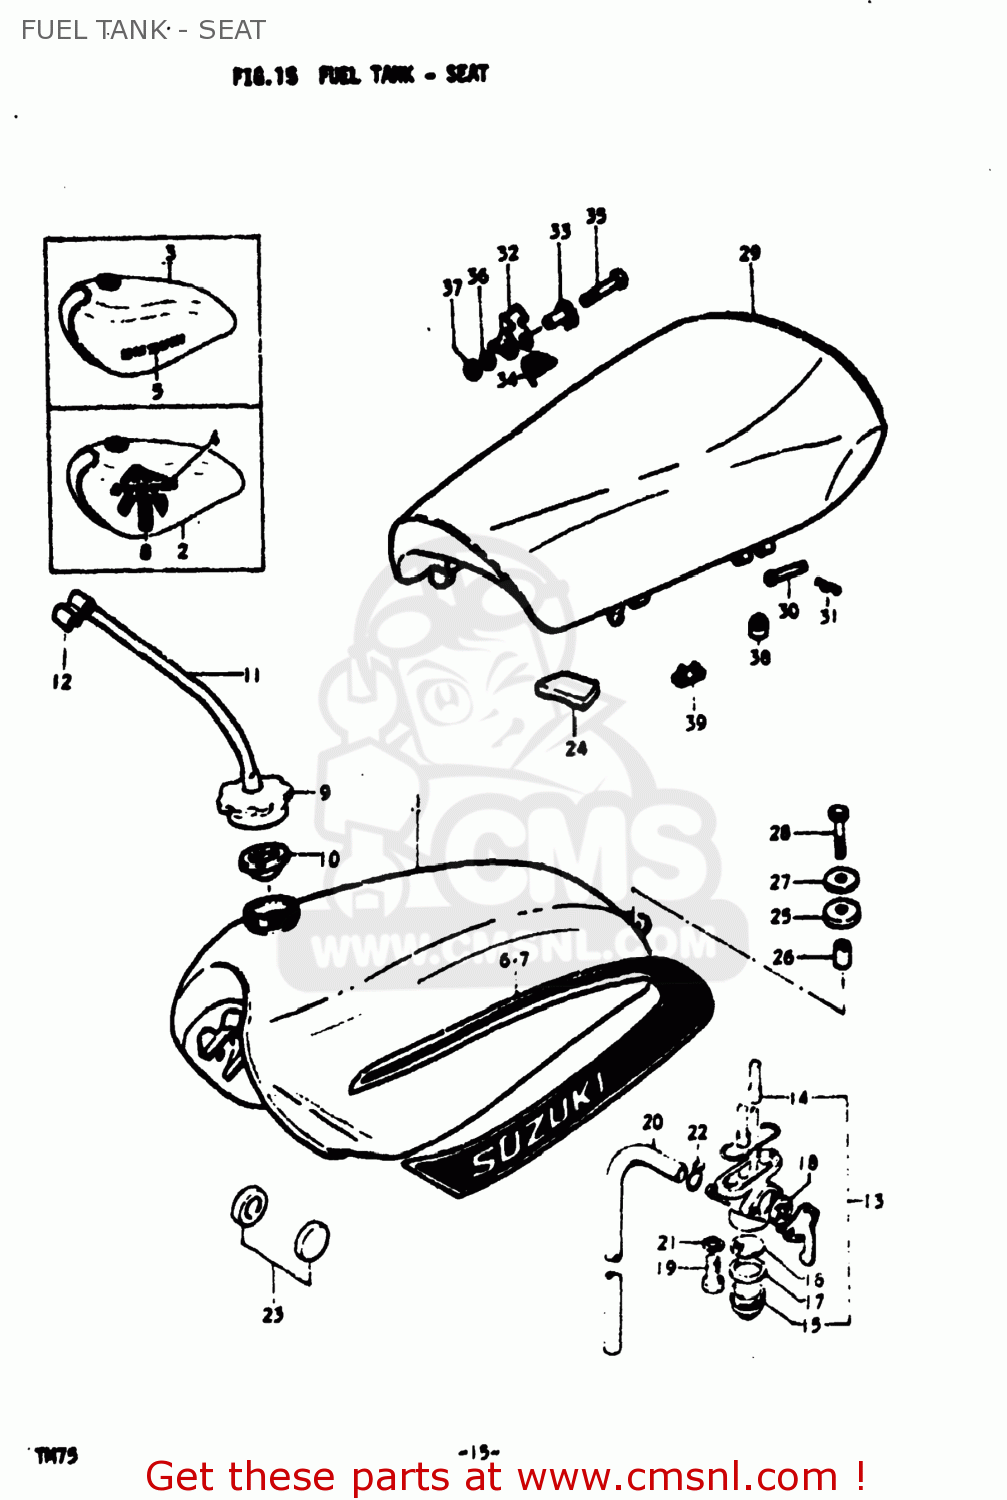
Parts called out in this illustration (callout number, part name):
1	TANK ASSEMBLY,FUEL
2	TANK ASSEMBLY,FUEL
3	TANK ASSEMBLY,FUEL
4	EMBLEM
5	EMBLEM
6	TAPE,FUEL TANK
7	TAPE,FUEL TANK
8	TAPE,FUEL TANK
9	CAP ASSY,FUEL TANK FILLER
10	GASKET,FUEL TANK CAP (NAS)
11	HOSE
12	CLAMP,FUEL
13	COCK ASSEMBLY,FUEL
14	FILTER SET,FUEL COCK
15	CUP,FUEL COCK STRAINER
16	NET,STRAINER
17	GASKET,FILTER (NAS)
18	GASKET,LEVER (NAS)
19	SCREW
20	HOSE
21	GASKET
22	CLIP
23	CUSHION
24	CUSHION
25	BUSH(12X15X20)
26	SPACER
27	WASHER (8.5X29X1.6)
28	BOLT
29	SEAT ASSEMBLY
30	PIN
31	CLIP
32	STRIKER,SEAT LOCK
33	STRIKER,SEAT LOCK
34	SPRING
35	BOLT 8X40
36	LOCK WASHER
37	NUT
38	CUSHION
39	CUSHION
